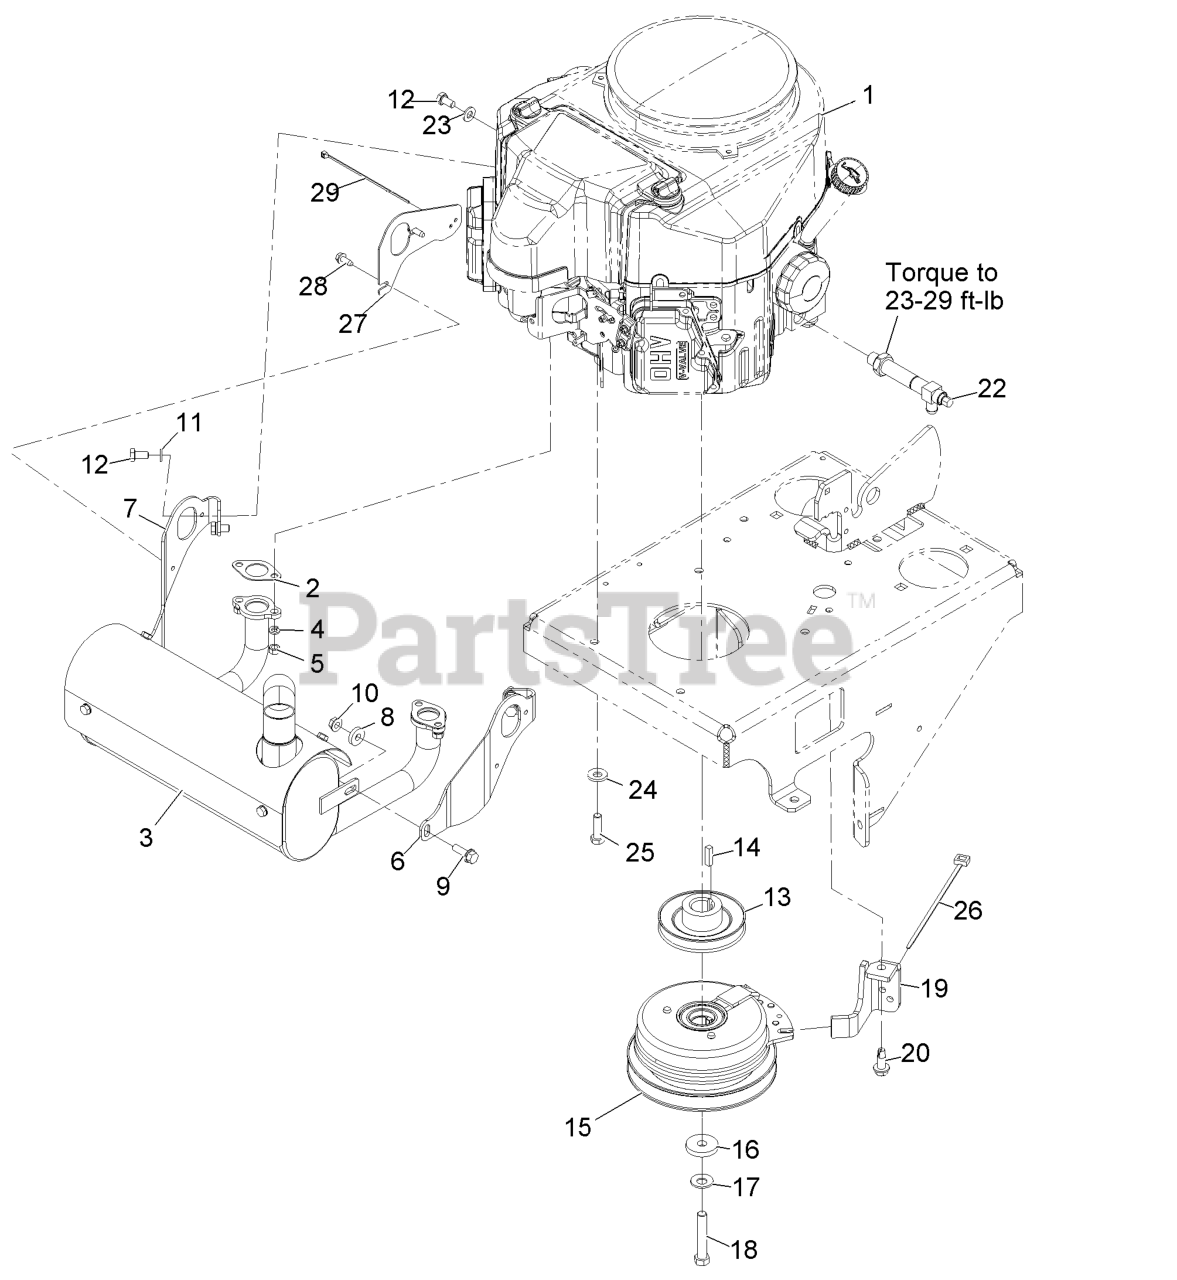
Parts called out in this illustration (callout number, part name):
2	GASKET-EXHAUST
4	WASHER-LOCK
6	BRACKET-MUFFLER MOUNT, LH
7	BRACKET-MUFFLER MOUNT, RH
9	SCREW-HHF
11	WASHER-LOCK
12	SCREW-HH
13	PULLEY
15	CLUTCH-175 FT-LB
16	WASHER
17	WASHER-SPRING
18	SCREW-HH
19	ANCHOR-CLUTCH
20	SCREW-TAPPING
23	WASHER-PLAIN
24	WASHER-BELLEVILLE
25	SCREW-HH
26	TIE-CABLE
27	GUARD-CABLE, SPARK PLUG
28	SCREW-HWH
29	TIE-CABLE
